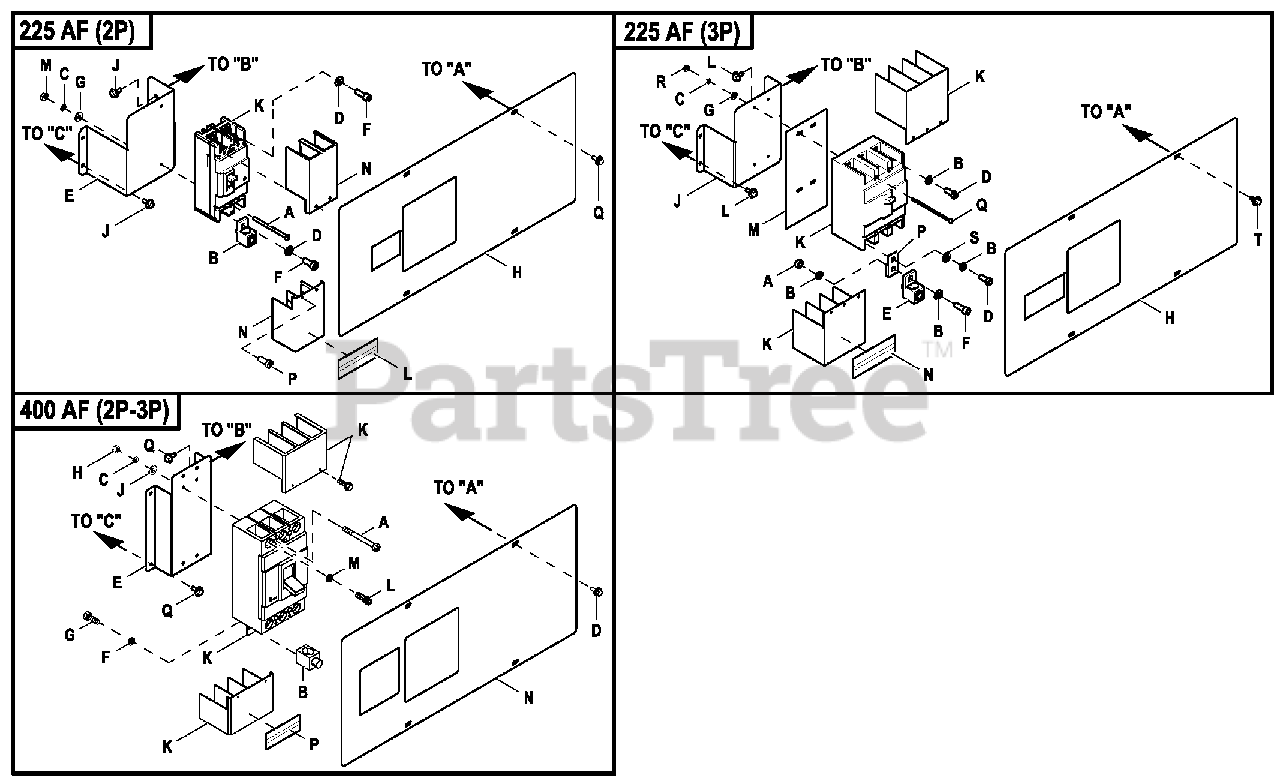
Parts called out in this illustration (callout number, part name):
A	SCREW RHM #8-32X2-1/2
B	LUG SLDLSS 350 MCM-6 AL/CU
C	WASHER LOCK #8-M4
D	WASHER LOCK M8-5/16
E	STANDOFF CB BOX CONBOX.PRT
F	SCREW SHC M8-1.25 X 20 G8
G	WASHER FLAT #8 ZINC
H	COVER PLATE CNTRL PNL 225AF 2P
J	SCREW HWHTF M6-1.0 X 16
K	CB 125A2POLE 240V225AF
L	DECAL TERMINAL SHOCK HZD BI
M	NUT HEX #8-32 STEEL
N	CB TERMINAL COVER 2 POLE 240V
P	SCREW PFH 4-24 X 5/16 TCS
Q	SCREW HWHT M6-1 X 16 N WA Z/JS
A	NUT HEX M8-1.25 G8 CLEAR ZINC
B	WASHER LOCK M8-5/16
D	SCREW SHC M8-1.25 X 20 G8
E	LUG SLDLSS 300 MCM-6 AL/CU
F	SCREW SHC M8-1.25 X 25 C12.9
H	COVER PLATE CNTRL PNL 225AF 3P
J	STANDOFF CB BOX CONBOX
K	CB 0050A 3P 480V G 225AF
L	SCREW HWHTF M6-1.0X 16
M	INSUL CB 225AF
N	DECAL TERMINAL SHOCK HZD BI
P	BUS BAR 200A LUG ADAPTOR
Q	SCREW RHM #8-32X3-1/4
R	NUT HEX #8-32 STEEL
S	WASHER FLAT 5/16-M8ZINC
T	SCREW HWHT M6-1 X 16 N WA Z/JS
A	SCREW RHM 10-32X4
B	LUG SLDLSS 600/250-1/0X1/4-28
C	WASHER LOCK #10
D	SCREW HWHT M6-1 X 16 N WA Z/JS
E	STANDOFF CB MOUNT CONBOX
F	WASHER LOCK M6-1/4
G	SCREW HHC 1/4-28 X 5/8 .625TH
H	NUT HEX #10-32 STEEL
J	WASHER FLAT #10 ZINC
K	CB 0250A 3P 480V G 400AF
L	SCREW SHCM10-1.5X25C12.9
M	WASHER LOCK M10
N	COVER PLATE CNTRL PNL 400AF 3P
P	DECAL TERMINAL SHOCK HZD BI
Q	SCREW HWHTF M6-1.0 X 16
